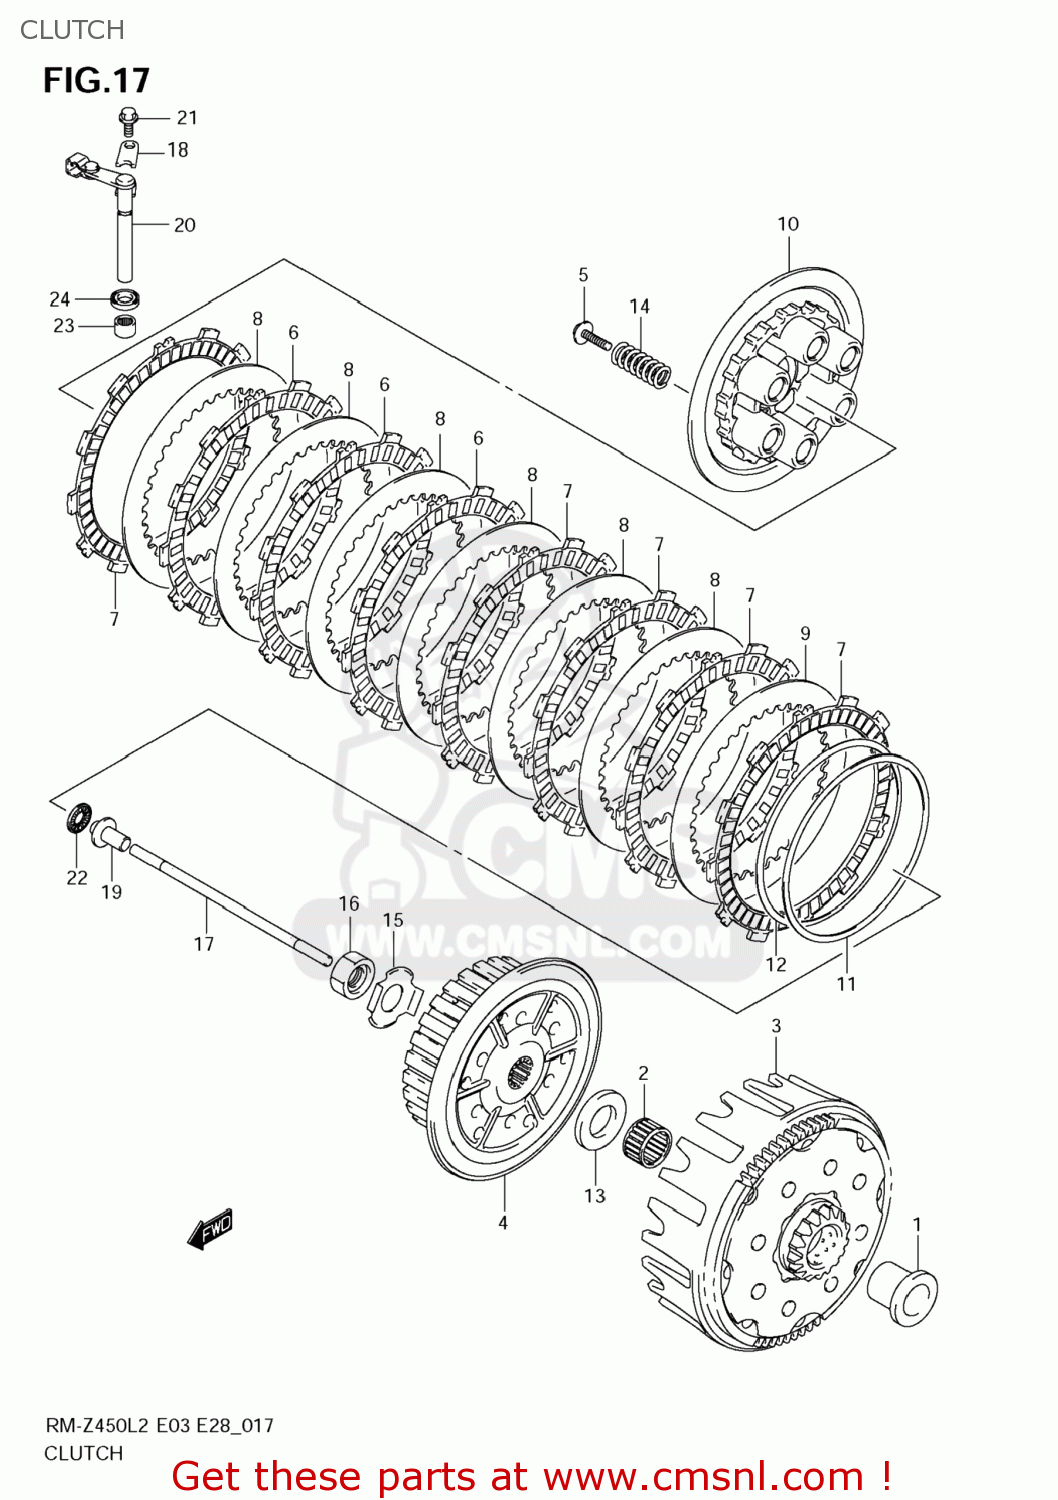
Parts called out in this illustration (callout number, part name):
1	SPACER,PRIMARY DRIVEN GEAR
2	BEARING(28X32X26)
3	GEAR ASSY,PRI DRIVEN
4	HUB,CLUTCH SLEEVE
5	BOLT,CLUTCH SPRING(6X25)
6	PLATE,CLUTCH DRIVEN NO.1 (NAS)
7	PLATE,CLUTCH DRIVE NO.2 (NAS)
8	PLATE,CLUTCH DRIVEN (NAS)
9	PLATE,CLUTCH DRIVEN (NAS)
10	DISC,CLUTCH PRESSURE
11	SEAT,WAVE WASHER
12	WASHER,CLUTCH PLATE WAVE
13	WASHER(22.5X39X3)
14	SPRING
15	WASHER,CLUTCH SLEEVE HUB LOCK
16	NUT
17	ROD,CLUTCH PUSH
18	RETAINER,CL RELEASE CAMSHAFT
19	PIECE,CLUTCH PUSH
20	CAMSHAFT,CLUTCH RELEASE
21	BOLT(6X12)
22	BEARING(10X22X2.8)
23	BEARING(10X14X10)
24	SEAL,OIL(10X17X5)
